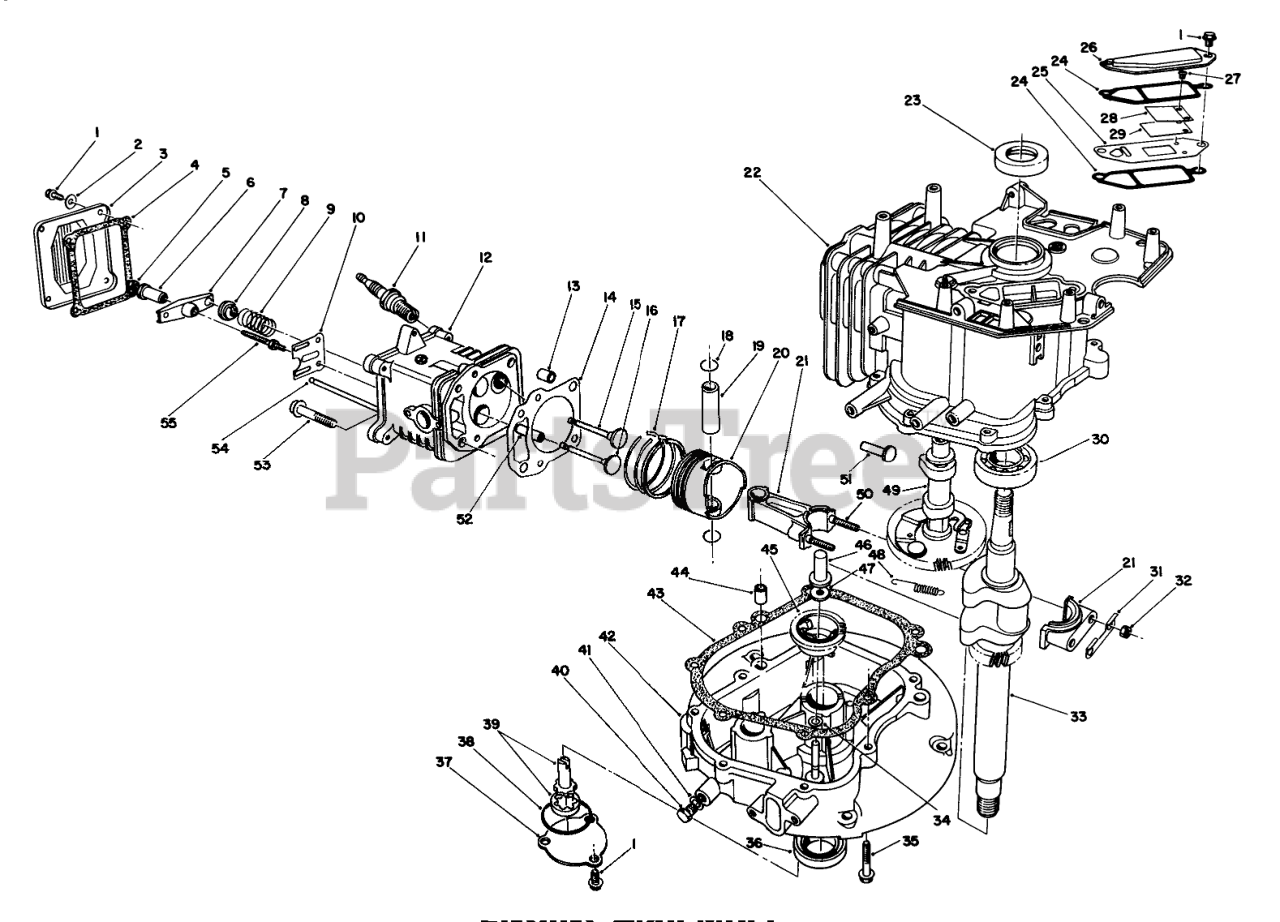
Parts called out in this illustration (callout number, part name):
2	WASHER
3	COVER
4	GASKET
6	PIVOT
8	RETAINER
9	SPRING
10	GUIDE
11	SPARK PLUG
12	Head-Cylinder (Incl. Ref. #52)
14	GASKET
15	VALVE-INTAKE
16	VALVE-EXHAUST
17	RING SET
18	CIRCLIP
20	PISTON
21	Connecting Rod Assembly (Incl. Ref. #31, 32, & 50)
22	Block-Engine (Incl. Ref. #23, & 30)
24	GASKET
25	Plate-Breather
26	COVER
27	Screw-Reed Valve
28	Retainer-Reed Valve
29	Valve-Reed
30	BEARING
31	Plate-Lock
33	CRANKSHAFT
34	WASHER
36	Oil Seal
37	COVER
38	O-RING
39	OIL PUMP
40	OIL DRAIN PLUG
41	GASKET
42	Crankcase
43	GASKET
45	GOVERNOR FLYWEIGHT ASM
46	PLUNGER
47	WASHER
48	SPRING
49	Camshaft Assembly (Incl. Ref. #48)
51	TAPPET
52	GUIDE
